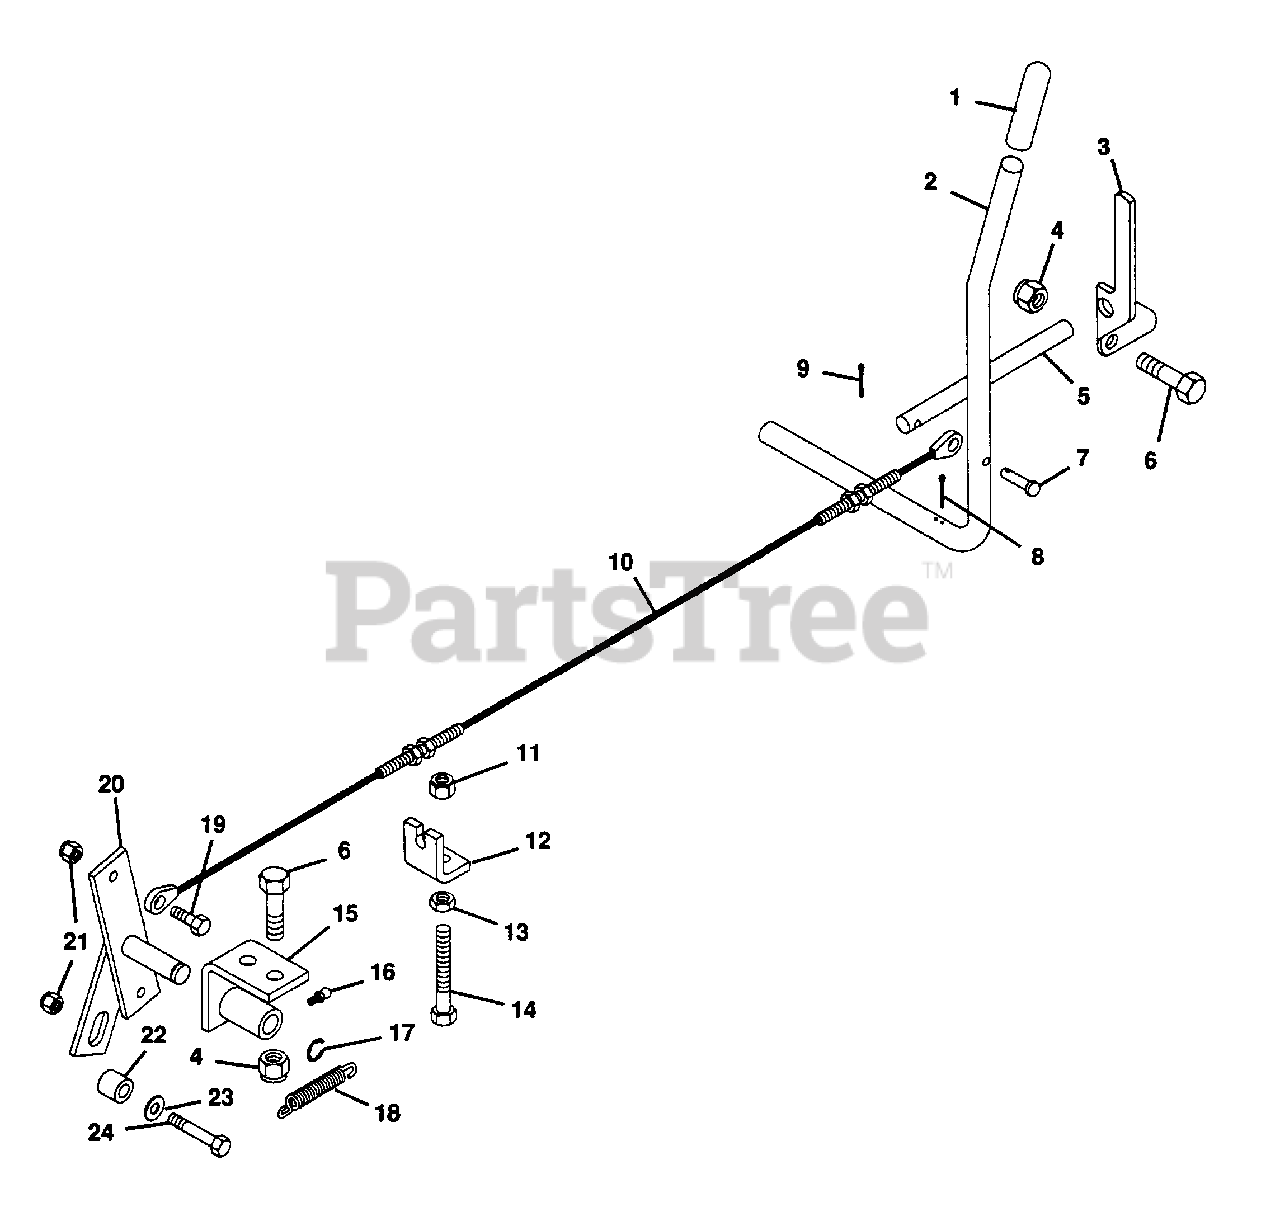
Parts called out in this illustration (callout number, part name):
1	GRIP, HANDLE
2	LEVER, BRAKE
3	ARM, PARKING BRAKE LOCK
4	NUT, LOCK 3/8-16
5	ROD, BRAKE LOCK
6	BOLT, HEX 3/8-16X1.00
7	PIN, CLEVIS
8	PIN, COTTER .094X1.25
9	PIN, COTTER .06X.75
10	CABLE, BRAKE
11	NUT, LOCK 5/16-18
12	BRACKET, CABLE
13	NUT, JAM 5/16-18 HEX
14	BOLT, HEX 5/16-18X3.25
15	WELDMENT, BRAKE PIVOT
16	FITTING, LUBE 1/4-28
17	E-RING, 5133-50
18	SPRING
19	BOLT, HEX 1/4-20X.875
20	WELDMENT, BRAKE ARM
21	NUT, LOCK 1/4-20
22	BUSH., ST. .260X.500X.750 STL.
23	WASHER, FLAT .281X.625X.065
24	BOLT, HEX 1/4-20X1.75
